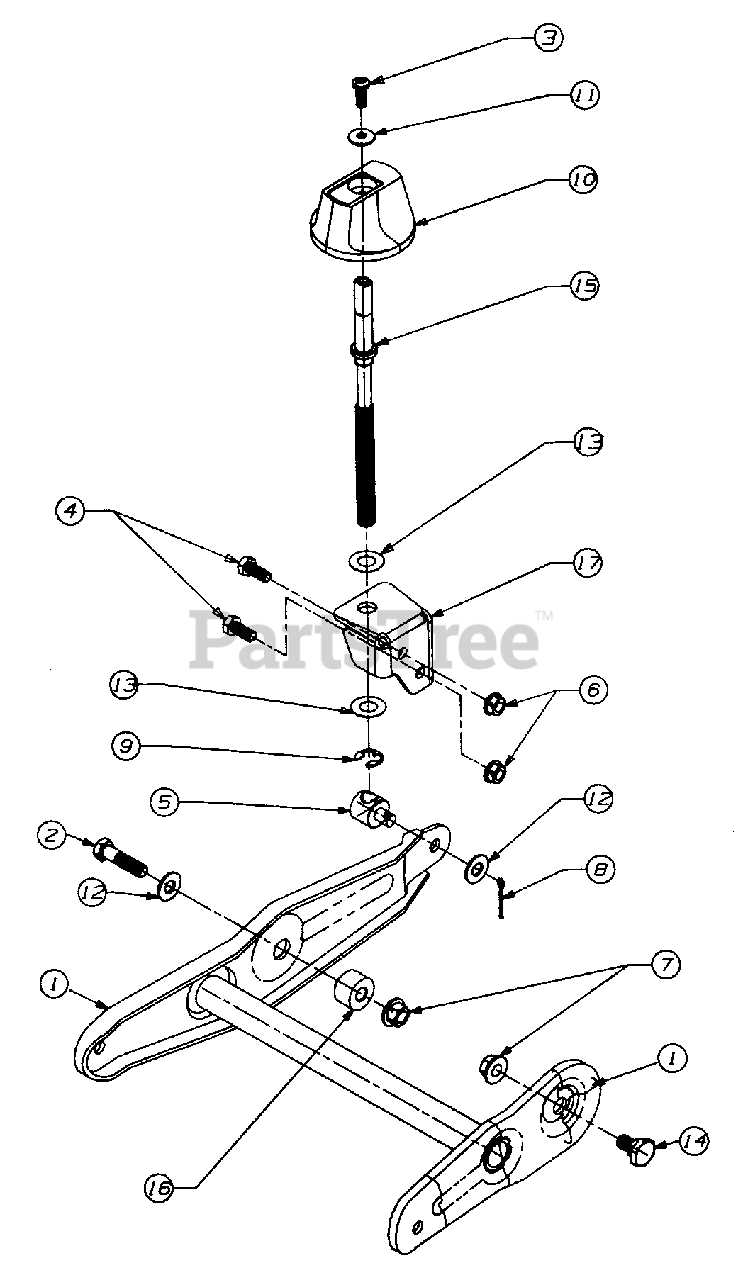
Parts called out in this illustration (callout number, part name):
3	SCREW - MACHINE PAN HD
4	SCREW - HEX
5	FERRULE - ADJUSTABLE
6	NUT - HEX FLANGE
7	NUT - HEX FLANGE LOCK
8	PIN - COTTER
9	RING - E
10	KNOB - PLASTIC
11	WASHER - BELL
12	WASHER - FLAT
13	WASHER - FLAT
14	SCREW - SHOULDER
15	ROD - ADJUSTABLE
16	SPACER
